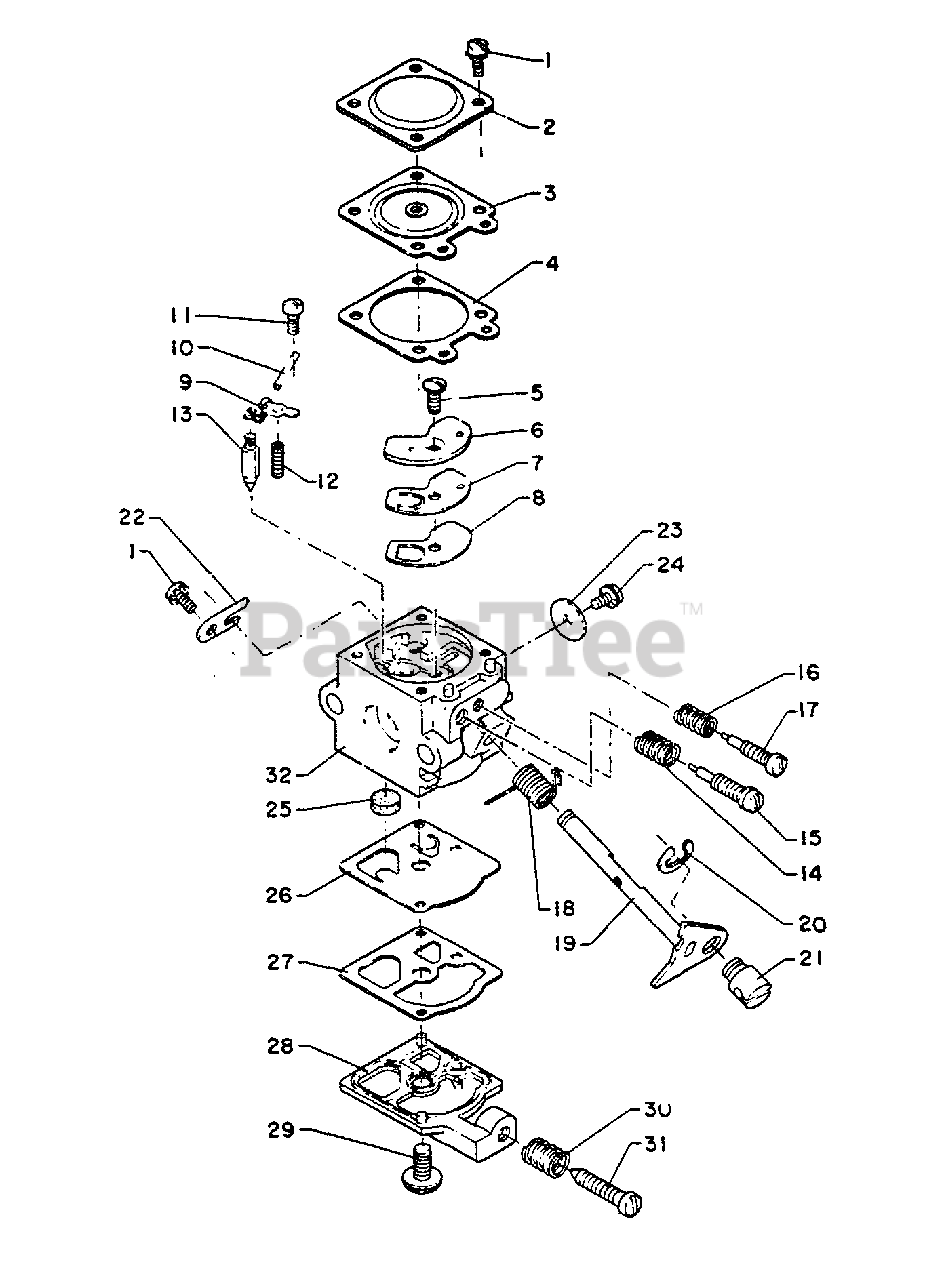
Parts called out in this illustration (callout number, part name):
2	COVER, METERING
3	DIAPHRAGM, METERING
4	GASKET, METERING
5	SCREW, CIRCUIT PLATE
6	PLATE, CIRCUIT
7	VALVE, CHECK
8	GASKET, CIRCUIT PLATE
9	LEVER, METERING
10	PIN, METERING LEVER
11	SCREW, METERING LEVER PIN
12	SPRING, METERING LEVER
13	VALVE, INLET NEEDLE
15	NEEDLE - HIGH SPEED
16	SPRING, IDLE ADJUST
17	NEEDLE - LOW SPEED
18	SPRING, THROTTLE RETURN
19	SHAFT, THROTTLE
20	RING, RETAINING
22	CLIP, THROTTLE SHAFT
23	VALVE, THROTTLE
25	STRAINER
26	DIAPHRAGM, PUMP
27	GASKET, PUMP
28	COVER, PUMP
29	SCREW, PUMP COVER
30	SPRING, IDLE ADJUST
31	SCREW, IDLE ADJUST
32	BODY, CARBURETOR
